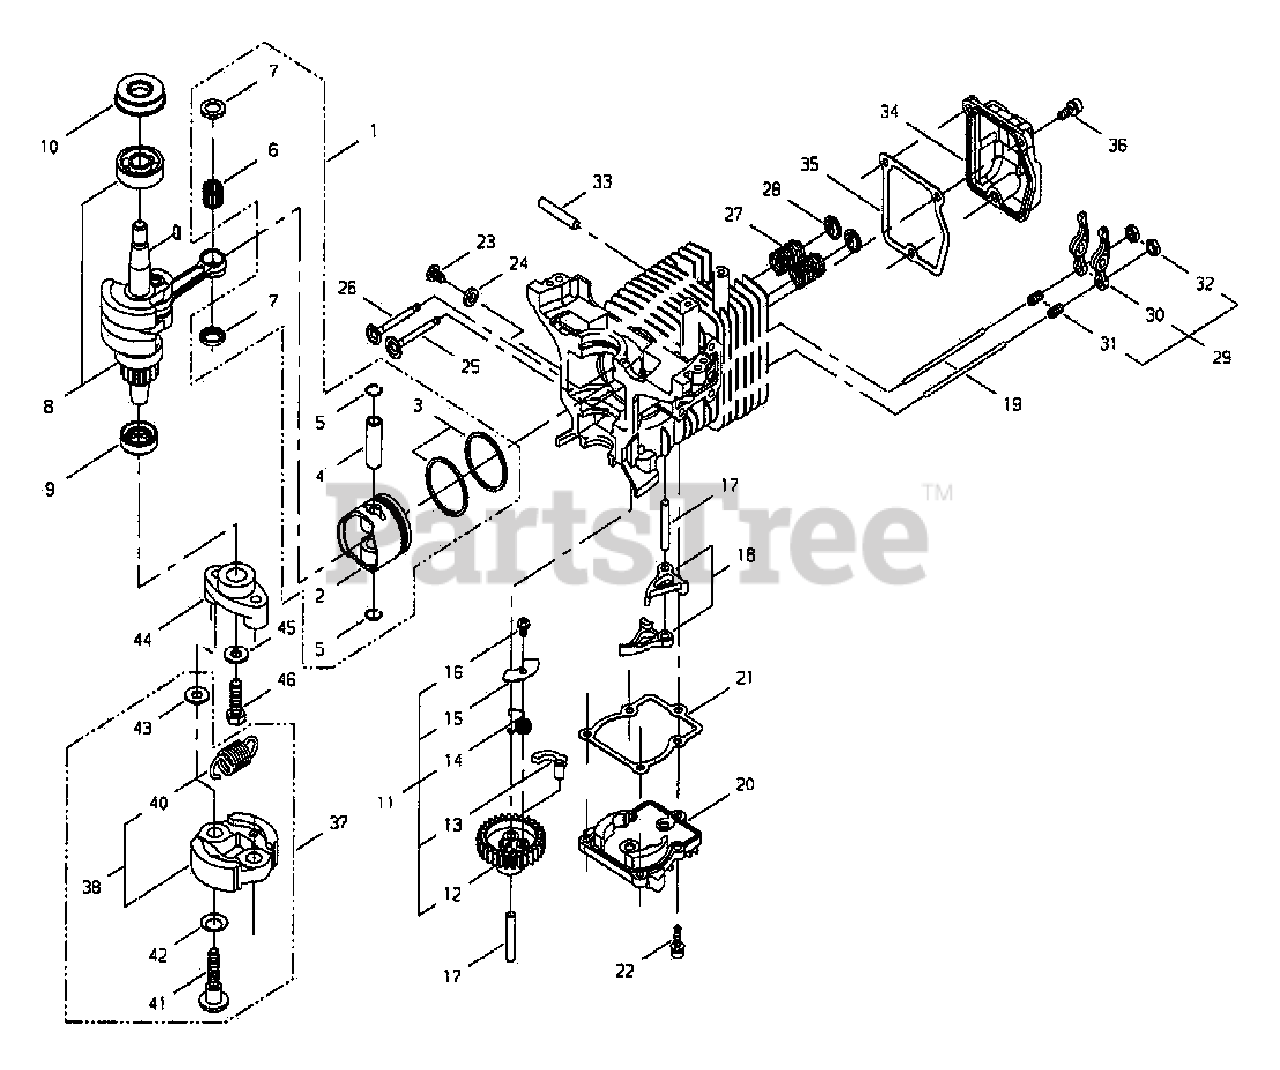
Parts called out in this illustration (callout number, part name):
1	PISTON KIT
2	PISTON
3	RING, PISTON
4	PIN, PISTON
5	RING, SNAP
6	BEARING, NEEDLE 9
7	WASHER, THRUST 9
8	CRANKSHAFT ASSY
9	SEAL, OIL 12
10	SEAL, OIL 12
11	CAM GEAR ASSY
12	GEAR, CAM
13	WEIGHT
14	SPRING
15	PLATE
16	SCREW, TAPPING 4×6
17	PIN, LOCATING Ø5×29.8 MM
18	FOLLOWER, CAM
19	PUSHROD
20	COVER, CAM GEAR
21	GASKET, CAM GEAR
22	BOLT M4×14
23	SCREW M5
24	WASHER Ø10ר5.5×2
25	VALVE, INTAKE
26	VALVE, EXHAUST
27	SPRING, VALVE
28	VALVE RETAINER ASSY
29	ARM ASSY, ROCKER
30	ARM, ROCKER
31	SCREW, ADJUSTER
32	NUT, ADJUSTER LOCK 5
33	SHAFT, ROCKER ARM Ø5×31.8 MM
34	COVER, ROCKER ARM
35	GASKET, ROCKER ARM
36	BOLT M4×12
37	CLUTCH KIT
38	SHOE ASSY, CLUTCH
40	SPRING, CLUTCH
41	BOLT, CLUTCH
42	WASHER, SPRING
43	WASHER 6 MM
44	BOSS, CLUTCH
45	WASHER 6 MM
46	BOLT M6×18
